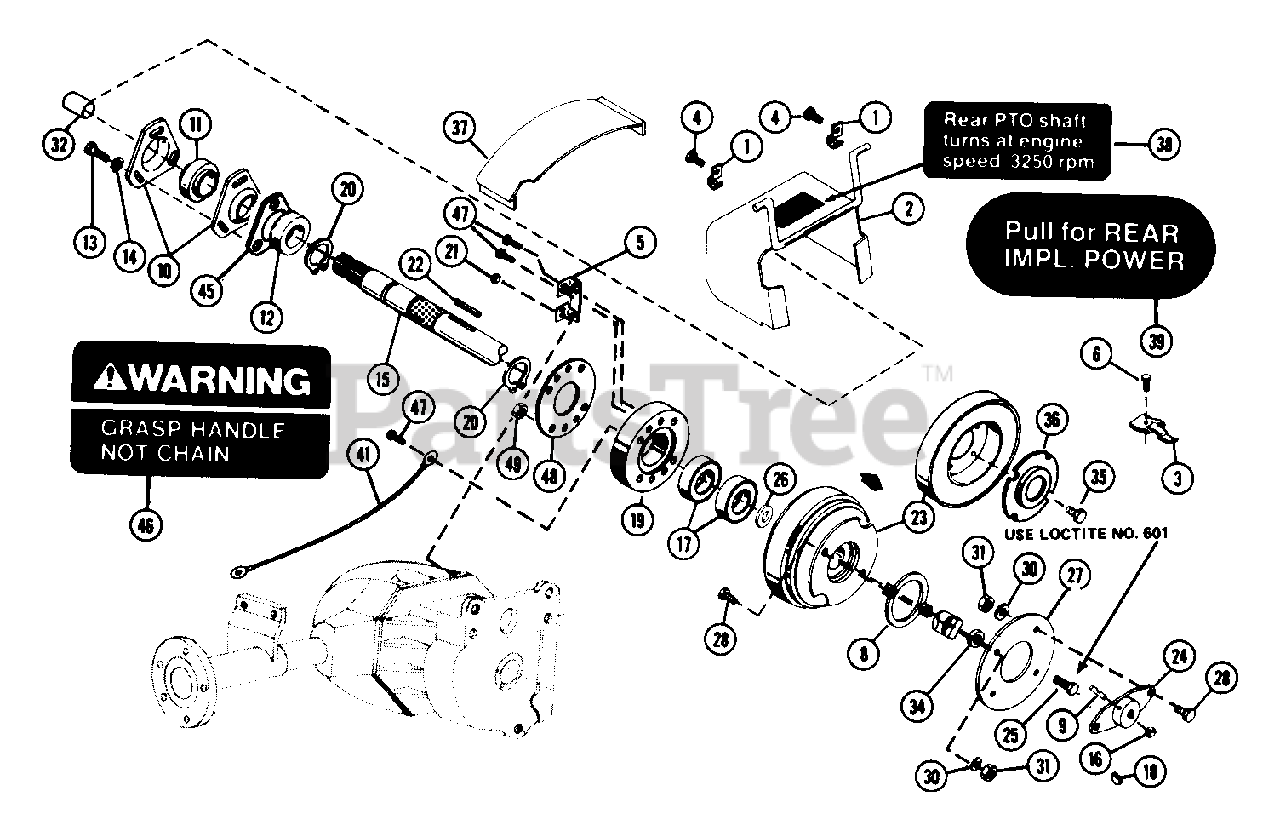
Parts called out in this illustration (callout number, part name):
2	PTO SHIELD
3	SNAP FASTENER
4	SCR-TAP .250-20X.50 HXSLHDPL
5	TORQUE BRACKET ASSEMBLY
6	SCR-TAP 10-24X.375 HWH PL TR
8	PILOT PLATE
9	LOCK STUD
10	BEARING FLANGE
11	BRG/W COLLAR 1.0 X 2.047 X.844
12	BEARING COLLAR
13	BLT-HEX .31-18X1.00 PL GR 2
14	WSHR-LK .312X.097 PL HVY
16	NUT-LK TOP .375-16 GR C YWZC
17	BRG-BALL 1.0X2.0X.56
18	KEY-WDRF .188X.75X.313 SAE 9
19	BEARING MOUNT
20	RG-RTNG-EXT 1.00X.078
21	NUT-LK-CTR .312-24 PL
22	KEY-SQ .25X1.0X.25 SAE 8630
23	ELECTRIC CLUTCH
24	COUPLING
25	BLT-BTHD .38-16X1.25 GR5
26	WSHR-FL-STL 1.031X1.375X.055
27	SPACER COUPLING
28	BLT-HEX .31-18X.75 PL GR2
30	WSHR-FL-STL.344X.688X.065PL
31	NUT-LK .312-18 GR A PL
32	SHAFT COVER
34	RETAINER
35	SCR-MCH 10-24X1.25 SLPAN PL
36	BEARING FLANGE
38	REAR PTO DECAL - 3200 RPM
39	REAR IMPLEMENT DECAL
41	GROUND WIRE
42	CLUTCH SWITCH
44	CLUTCH HARNESS
46	CHAIN WARNING DECAL
47	SCR-TAP 10-24X.75 HWH PL TR
49	NUT-LK TOP 10-24 PL
